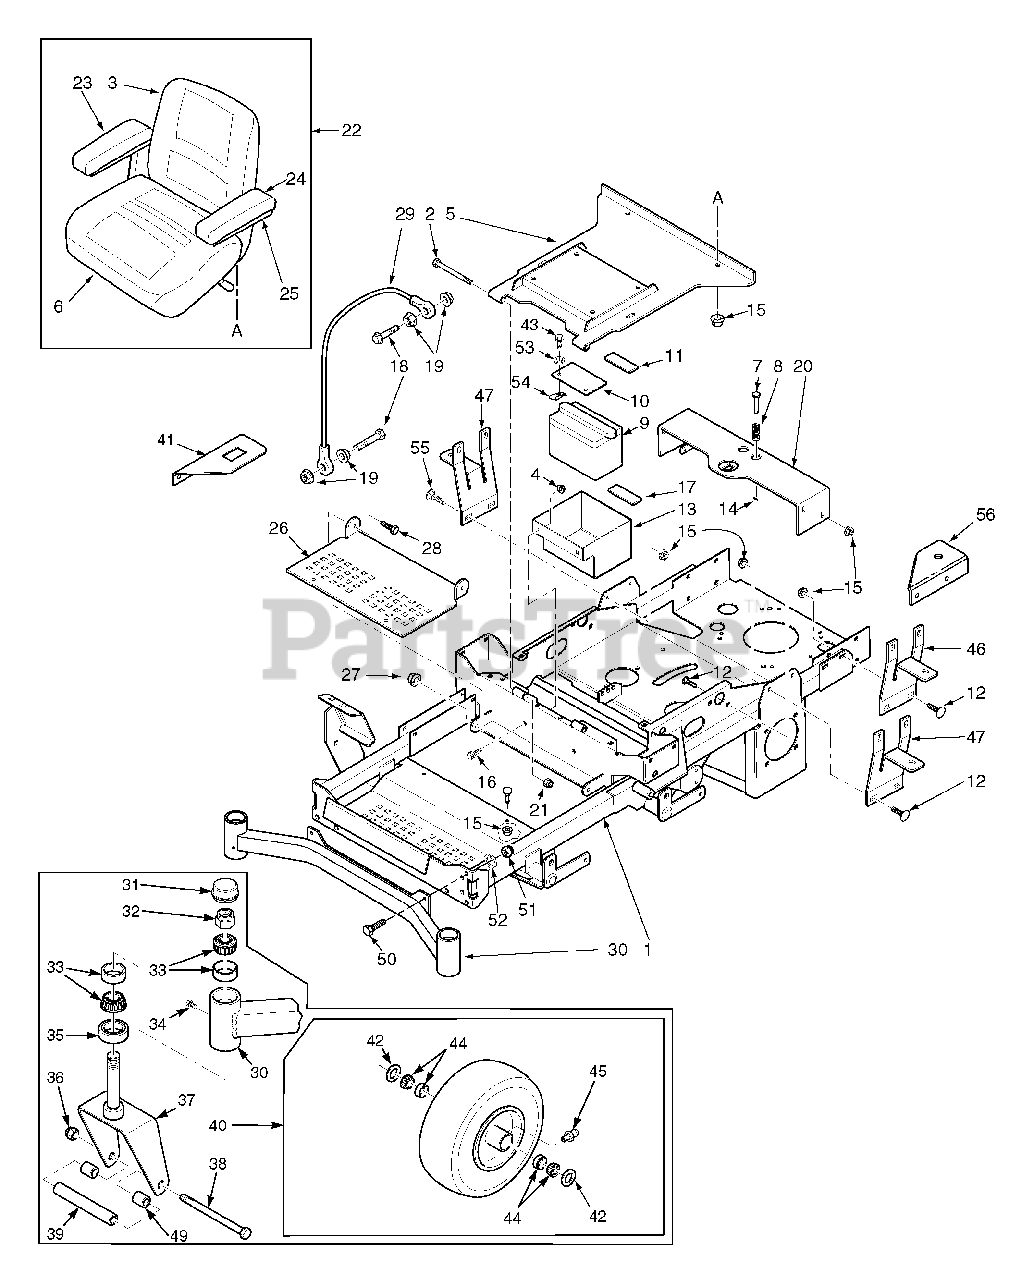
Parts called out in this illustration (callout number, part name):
1	Main Frame Assembly w/decals
2	Bolt, Hex Head 5/16-18 x 3-3/4"
3	Cushion, Back
4	Nut, Serr. Flange 3/8-16
5	Plate, Seat Mounting
6	Cushion, Lower Seat
7	Pin Retainer, Spring
8	Spring
9	Battery
10	Battery Cover
11	Battery Hold Down Pad
12	Bolt, Carr. 5/16-18 x 3/4"
13	Battery Box
14	Roll Pin, Spring 5/32 x 3/4"
15	Nut, Serr. Flange 5/16-18
16	Bolt, Hex Head 3/8-16 x 1"
17	Pad, Rubber
18	Bolt, Hex Head 1/4-20 x 1-1/4"
19	Nut, Serr. Flange 1/4-20
20	Seat Base Support
21	Nut, Elastic Stop 5/16-18
22	Seat Assembly w/ adj. rails
23	Arm Pad, RH
24	Arm Pad, LH
25	Channel, Armrest
26	Footplate
27	Nut, Elastic Stop 3/8-16
28	Bolt, Hex Head 3/8-16 x 1"
29	Cable, Seat Stop
30	Weldment, Caster Support
31	Cap, Grease
32	Nut, Elastic Stop 1.0-14
33	Bearing Set
34	Plug, 1/4-28
35	Seal, 2.0" OD x 1.625" ID
36	Nut, Elastic Stop 1/2-13
37	Yoke, Front Caster Wheel
38	Bolt, Hex Head 1/2-13 x 7-1/2"
39	Sleeve
40	Caster Wheel Assembly
41	Bracket, Hour Meter
43	Bolt, Hex Head 3/8-16 x 1-1/4"
44	Roller Bearing
45	Fitting, Grease
46	Mounting Bracket, Oil Tank
47	Mounting Bracket, Fuel Tank
48	Seat Pan
49	Spacer, Caster Wheel
50	Bolt, Hex Head 7/16-14 x 1-1/4"
51	Nut, Elastic Stop 7/16-14
52	Lockwasher, 7/16
53	Lock Washer. 3/8 Spring
54	U-Nut, 3/8-16
55	Bolt, Carriage 5/16-18 x 1"
56	Bracket, Fuel Valve
